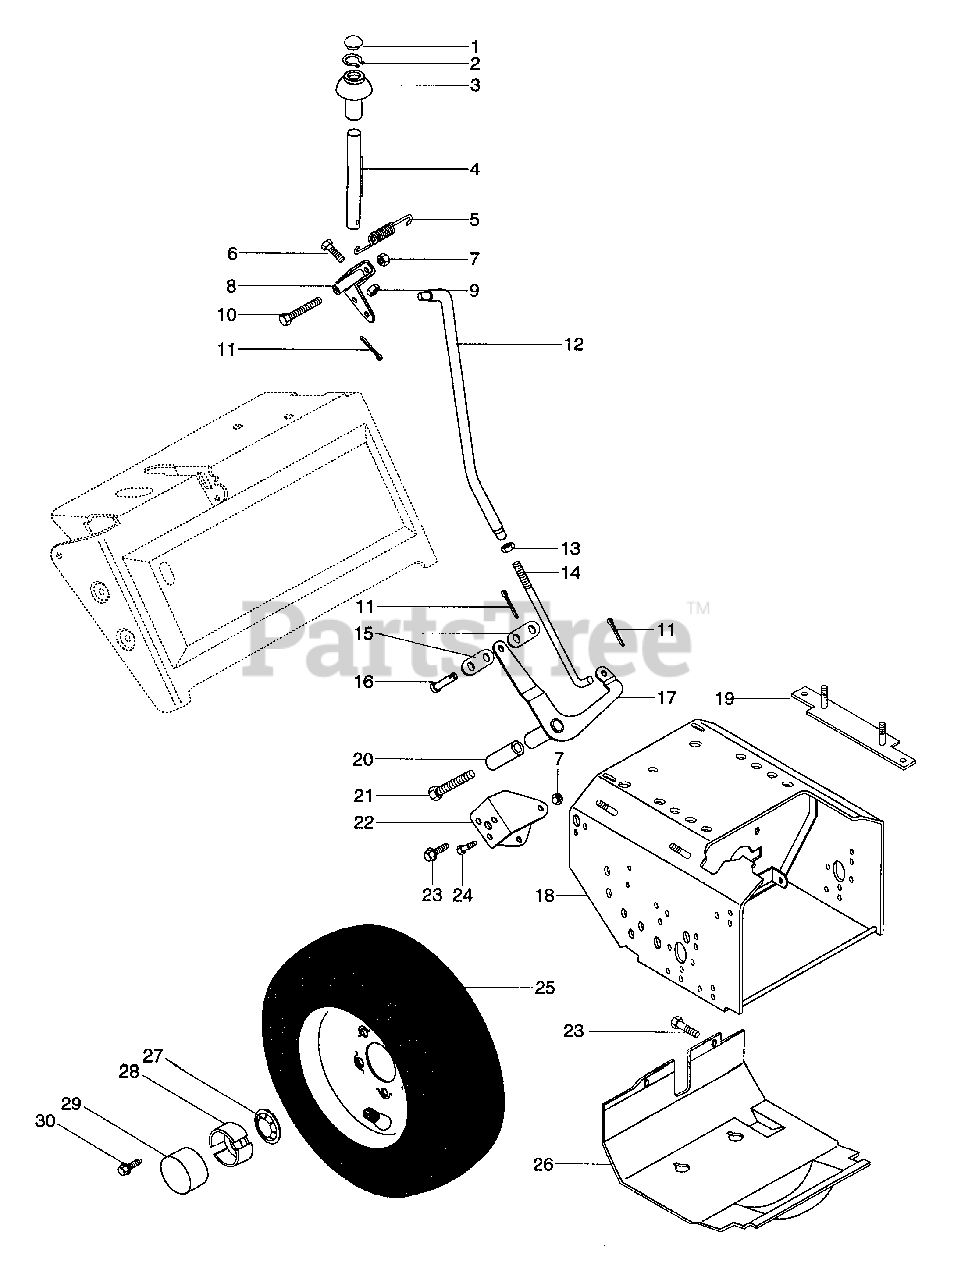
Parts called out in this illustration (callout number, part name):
1	HOLE PLUG
2	RG-RTNG-EXT .500X.015
4	ROD
5	SG-TENS .055X.33X1.31 WLD 7
6	BLT-HEX .25-20X1.00 GR2
7	NUT-LK .312-18 GR A PL
9	NUT-LK-CTR .250-20 PL
10	BLT-HEX .31-18X3.50 PL GR2
11	PIN-COTR .09X.75 PL
12	UPPER SHIFT ROD
13	NUT-HEX .312-24 YWZC
14	LOWER SHIFT ROD
15	SHIFT LINK
16	CLEVIS PIN
17	LEVER - SHIFT ARM
18	FRAME
19	BOLT STRAP
20	SPACER .5 X .33 X 2.4
21	BLT-HEX .31-18X3.00 PL GR2
22	BRACKET SHIFT LEVER
23	SCR-TAP .312-18X.50 HWH PL TR
24	BLT-HEX .31-18X.50 PL GR2
25	TUBE
25	WHL
25	TIRE 4.80-8 NHS
25	TIRE 16X6.50-8 SNO-HOG TREAD
25	T/WHL ASSY 4.80-8
25	T/WHL ASSY 16X6.50-8 SNO-HOG
26	BOTTOM COVER
27	PUSHNUT
28	SPINDLE CUP
29	HUB CAP
30	SCR-TAP .500-20X.62 HH PL
